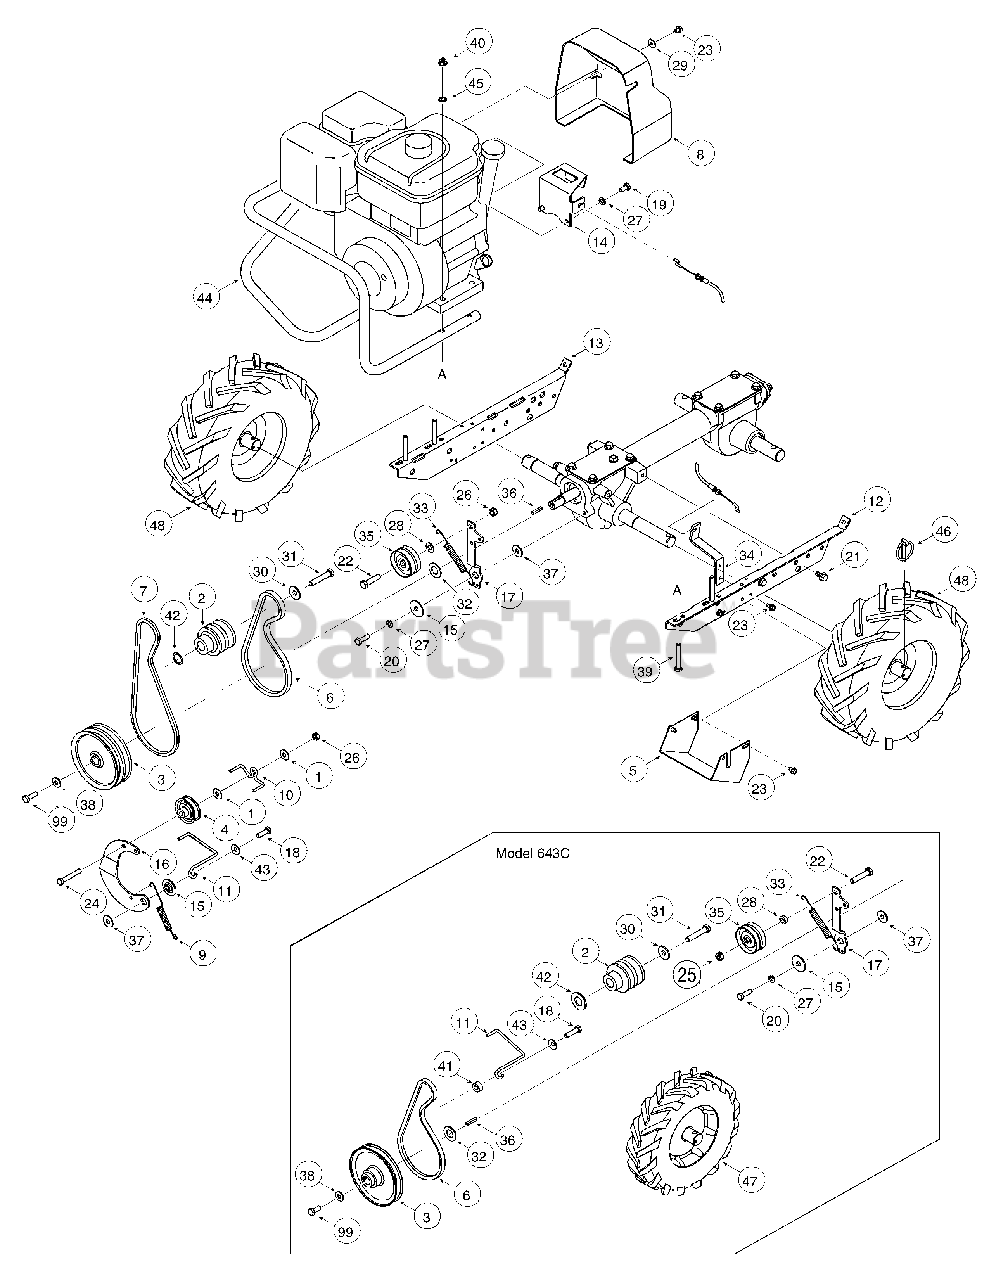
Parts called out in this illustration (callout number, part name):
1	Flat Washer, 5/16
2	Pulley, Engine Drive
3	Transmission Pulley (for model 643C)
3	Transmission Pulley (for models 643B and 645A)
4	Pulley, Reverse Idler (for models 643B and 645A)
7	Reverse Drive Belt (for models 643B and 645A)
8	Belt Cover
9	Reverse Return Spring (for models 643B and 645A)
10	Belt Guide (for models 643B and 645A)
11	Belt Guide
12	Engine Bracket, Left
13	Engine Bracket, Right
16	Reverse Idler Arm (for models 643B and 645A)
18	Hex Hd. Screw, 5/16-24 x 1.25 (for model 643C)
18	Hex Hd. Screw, 5/16-24 x 1 (for models 643B and 645A)
19	Hex Hd. Screw, 5/16-24 x 5/8
20	Hex Hd. Screw, 5/16-18 x 1
21	Hex Hd. Screw, 5/16-18 x 5/8
22	Hex Hd. Screw, 3/8-16 x 1-3/4 (for model 643C)
22	Hex Hd. Screw, 3/8-16 x 1.50 (for models 643B and 645A)
23	Screw, Self-Tapping, 1/4-20 x 1/2
24	Hex Hd. Screw, 5/16-18 x 2 (for models 643B and 645A)
25	Lock Nut, 3/8-16
26	Lock Nut, Hex Center (for models 643B and 645A)
27	Lock Washer, 5/16 (for model 643C)
28	Spacer, .380 ID x .625 OD x .21 (for model 643C)
28	Flat Washer .406 x .812 x .051 (for model 645A)
29	Flat Washer
30	Bell Washer
31	Hex Hd. Screw, 3/8-24 x 1.50, GR5
32	Support Washer
33	Forward Return Spring
36	Key, 3/16" x 1"
37	Flat Washer
38	Belleville Washer
39	Hex Screw, 5/16-18 x 1.50 Gr5 (for models 643C and 643B)
39	Hex Screw, 5/16-18 x 2-1/4, Gr5 (for model 645A)
40	Nut, Hex Lock, 5/16-18
41	Spacer, Shoulder (for model 643C)
42	Washer, Flat, .75 x 1.5 x .125 (for model 643C)
42	Flat Washer .786 x 1.000 x .031 (for models 643B and 645A)
43	Bell Washer
45	Nut, Speed, 5/16-18 for models 645A)
46	Klik Pin
47	Complete Wheel Assembly 10 x 2.75 (for model 643C)
48	Complete Wheel Assembly 13 x 5 x 6 for models 643B and 645A)
48	Rim Assembly (for models 643B and 645A)
48	Air Valve (for models 643B and 645A)
99	Hex Hd. Screw, 5/16-24 x 1
